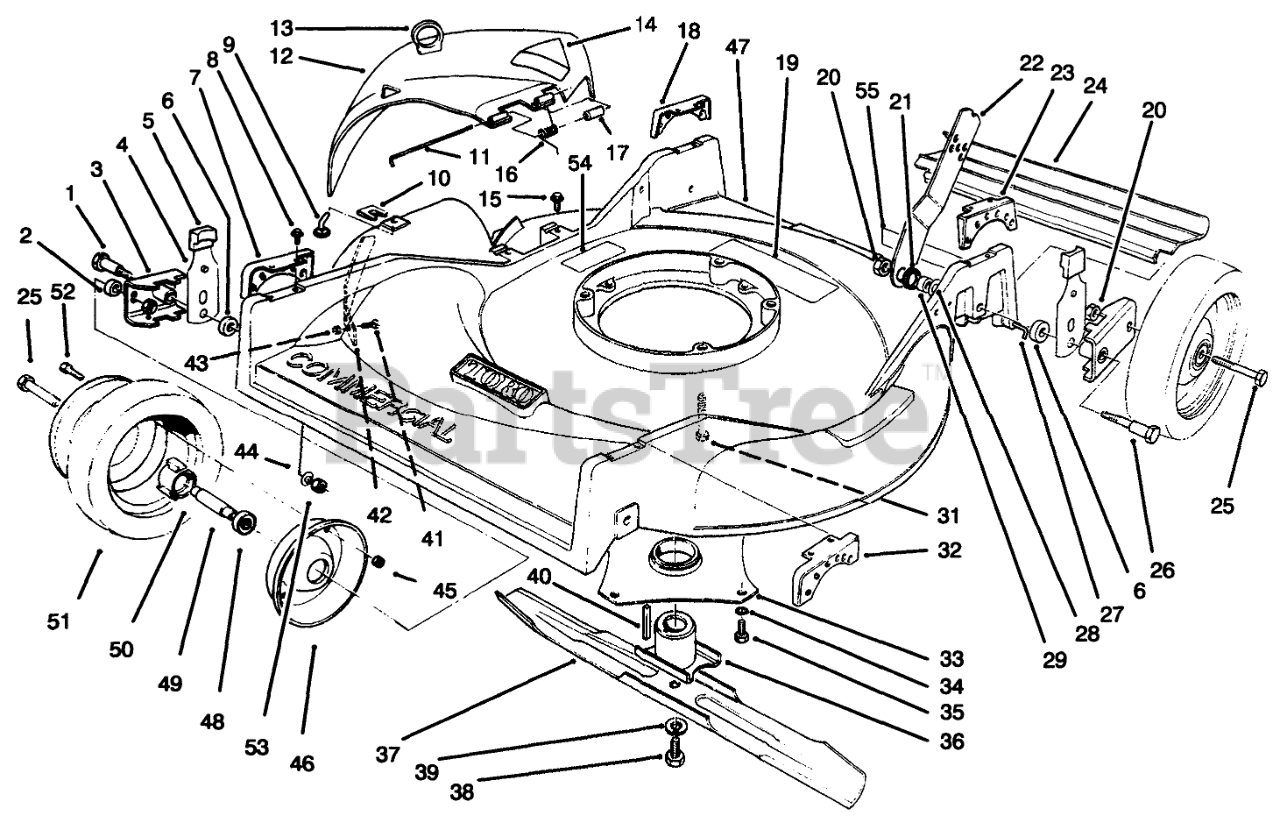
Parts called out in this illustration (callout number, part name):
1	PIVOT SCREW
2	SPACER-WHEEL
3	PIVOT ARM
4	SPRING ARM ASM-FRONT
5	KNOB-ARM
6	SPACER-PIVOT
7	FRT RIGHT QUAD
8	Screw-Thread Forming
9	Pin-Chute
10	Clip-Pin
11	Pin-Deflector Hinge
12	Deflector (Incl. Ref. #14)
13	Loop-Lift
14	Decal-Danger
15	Screw/Washer Assembly
16	Spring-Deflector
17	Sleeve-Spring
18	REAR RIGHT QUAD
19	DECAL-INSTRUCTION, SAFETY
20	NUT-LOCK, NI
21	HANDLE LATCH SPACER
22	Latch-Handle
23	REAR LEFT QUAD
24	SHIELD - TRAILING
25	SCREW-HH
26	REAR PIVOT SCREW
27	SHIELD ROD
28	WASHER-BELLEVILLE
29	HANDLE LATCH SPACER
31	Screw-Flange Head
32	FRT LEFT QUAD
33	CRNKSHFT PROTECT ASM
34	WASHER-LOCK, INTERNAL
35	SCREW-HWHTF
36	RETAINER-BLADE
37	Blade
38	SCREW-HH
39	WASHER-LOCK
40	KEY-SQUARE
41	SCREW-CARR
42	Bar-Safety
43	NUT-LOCK, NI
44	WASHER-BELLEVILLE
45	NUT-LOCK, NI
46	Wheel-Half
47	Housing (Incl. Ref. #19, 54 & 55)
48	BEARING-WHEEL
49	SPACER-BEARING
50	HUB-BEARING
52	SCREW-HH
53	NUT-LOCK, CONE
54	DECAL - DANGER, COVERS
55	DECAL-WARNING
